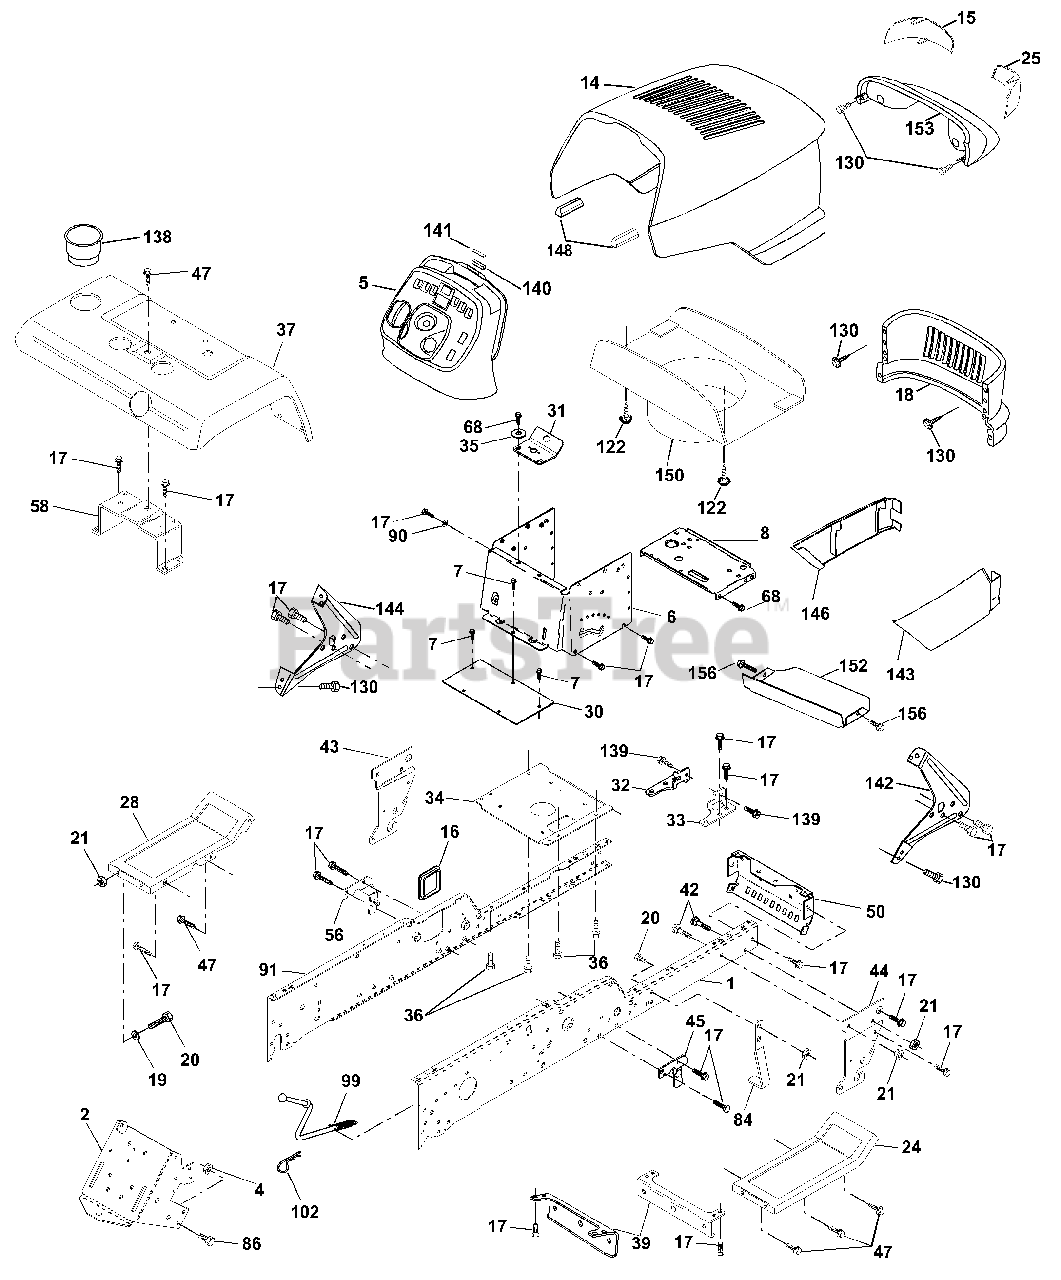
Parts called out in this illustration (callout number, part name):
1	Rail, Frame RH
2	Drawbar, Gt
4	Nut, Lock Hex 7/16 Unc
5	Dash, Plastic
6	Dash, 1PCS, Lower
7	Screw, Thd Cut 1/4-20 x 1/2
8	Support, Battery
14	Hood Asm., Pnt
15	Lens RH
16	Cover, Access
17	Screw, 3/8-16 x 3/4
18	Grille
19	Washer 13/32 x 13/16 x 12 Ga.
20	Bolt, Fin Hex 3/8-16 x 1
21	Nut, Crownlock 3/8-16
24	Footrest, RH
25	Lens LH
28	Footrest, LH
31	Bracket Supt 1-pc Vgt Steering
32	Bracket, Frame Pivot Lh
33	Bracket, Frame Pivot Rh
34	Plate Asm Engine Chassis
35	Washer 11/32 x 11/16 x 16 Ga.
36	Screw 5/16-18 x 3/4
37	Fender, Pnt.
39	Bracket, Axle Front
42	Bolt Rdhd Sqnk 3/8-16 Unc x 1
43	Bracket, Spnsn Front Lh
44	Bracket, Spnsn Front Rh
45	Bracket Asm., Susp Chassis Rh
47	Screw Thdrol 3/8-16 x 1/2
50	Bracket, Chassis Front
56	Bracket Asm., Susp Chassis Lh
58	Bracket Asm., Fender
68	Screw, 5/16-18 x 1/2
84	Stop, Over Center Mower
86	Bolt, Fin Hex 7/16-14 Unc x 1
90	Washer, Lock External Tooth 3/8
91	Rail, Frame Lh
99	Rod Asm. Bypass
102	Retainer Spring 1"
122	Screw Hex WSHD 8-18 x 7/8
130	Screw Hw Hd Hi-Lo #13-16 x 3/4
138	Cupholder
139	Bolt Shoulder 5/16-18
140	Magnet Stealth
141	Striker Plate
142	Bracket Dash Stealth RH
143	Skirt Grille RH
144	Bracket Dash Stealth LH
146	Skirt Grille LH
148	Extrusion Bumper
150	Duct Heat Hood
152	Shield, Browning
153	Lens, Headlight Bar
156	Screw 5/16-18 x 3/4
